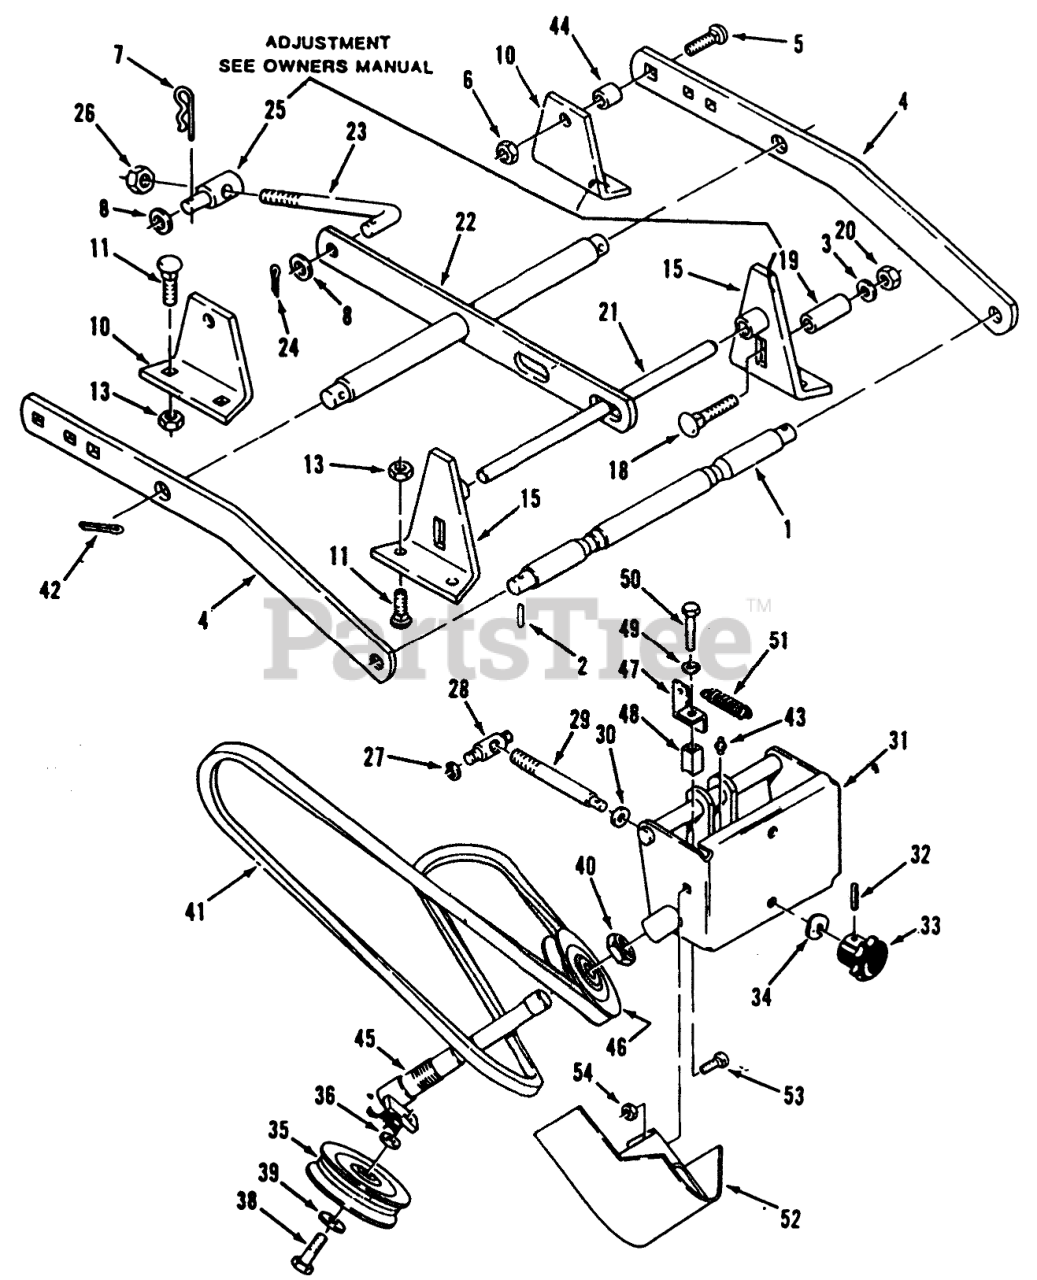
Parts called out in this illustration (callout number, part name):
1	Shaft
3	Washer
4	Bar-Draft
5	Bolt-Carriage
6	LOCKNUT-FLANGE
7	Hairpin
8	Washer
10	Rear Deck Bracket
11	Bolt
13	NUT
15	Front Deck Bracket
18	CARRIAGE BOLT -4
19	SPACER
20	Nut
21	Front Shaft
22	Leveler
23	ROD LEVELER
24	Cotter Pin
25	TRUNION
26	Nut
27	RING-RETAINING
28	TRUNNION-DOUBLE
29	ROD ADJ
30	Washer
31	Front Idler Support
32	PIN-ROLL
33	KNOB-ADJUSTMENT
34	WASHER-SPRING
35	PULLEY-FLAT IDLER
36	SPACER
38	BOLT
39	Washer
40	Nut
41	BELT-103" A SECTION
42	Cotter Pin 1/8 x 1 1/4
43	Grease Zerk
44	SPACER
45	ASS'Y-IDLER ARM
46	Pulley-V
47	Bracket
48	BLOCK-GUIDE
49	Lock Washer 5/16
50	Bolt
51	SPRING-BRAKE
52	Cover
53	Bolt
54	Nut
55	Pulley Box Assembly
